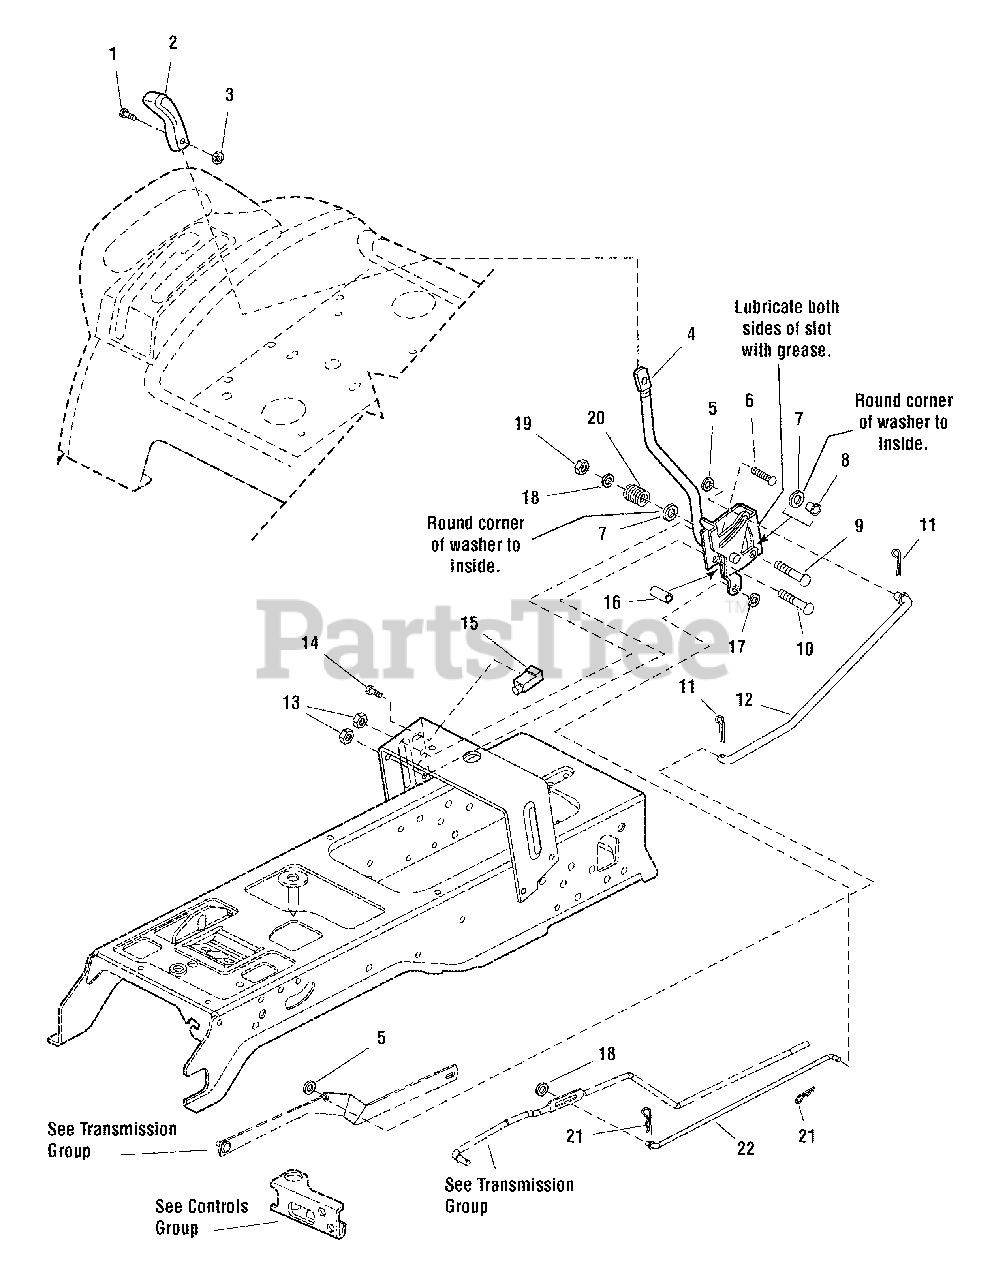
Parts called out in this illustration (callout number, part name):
1	CAPSCREW, Torx Socket Head, 1/4-20 x 7/8
2	KNOB, Cruise
3	NUT, Hex ESNA Lock, 1/4-20
4	LEVER & BRACKET ASSEMBLY, Cruise
5	WASHER
6	CARRIAGE BOLT, 5/16-18 x 3/4
7	WASHER, 9/16 x 1-1/4 x 1/8
9	CARRIAGE BOLT, 5/16-18 x 2-3/4
10	CARRIAGE BOLT, 5/16-18 x 2-1/4
11	PIN, Cotter
12	ROD, Cruise
13	NUT, Hex KEPS, 5/16-18
14	CAPSCREW, Hex Head Plastite, 10-14 x 5/8
15	SWITCH, Push, Neutral Start, Gray
18	WASHER
19	NUT, Hex ESNA Lock, 5/16-18
20	SPRING, Compression
21	PIN, Quick
22	ROD, Cruise Return
